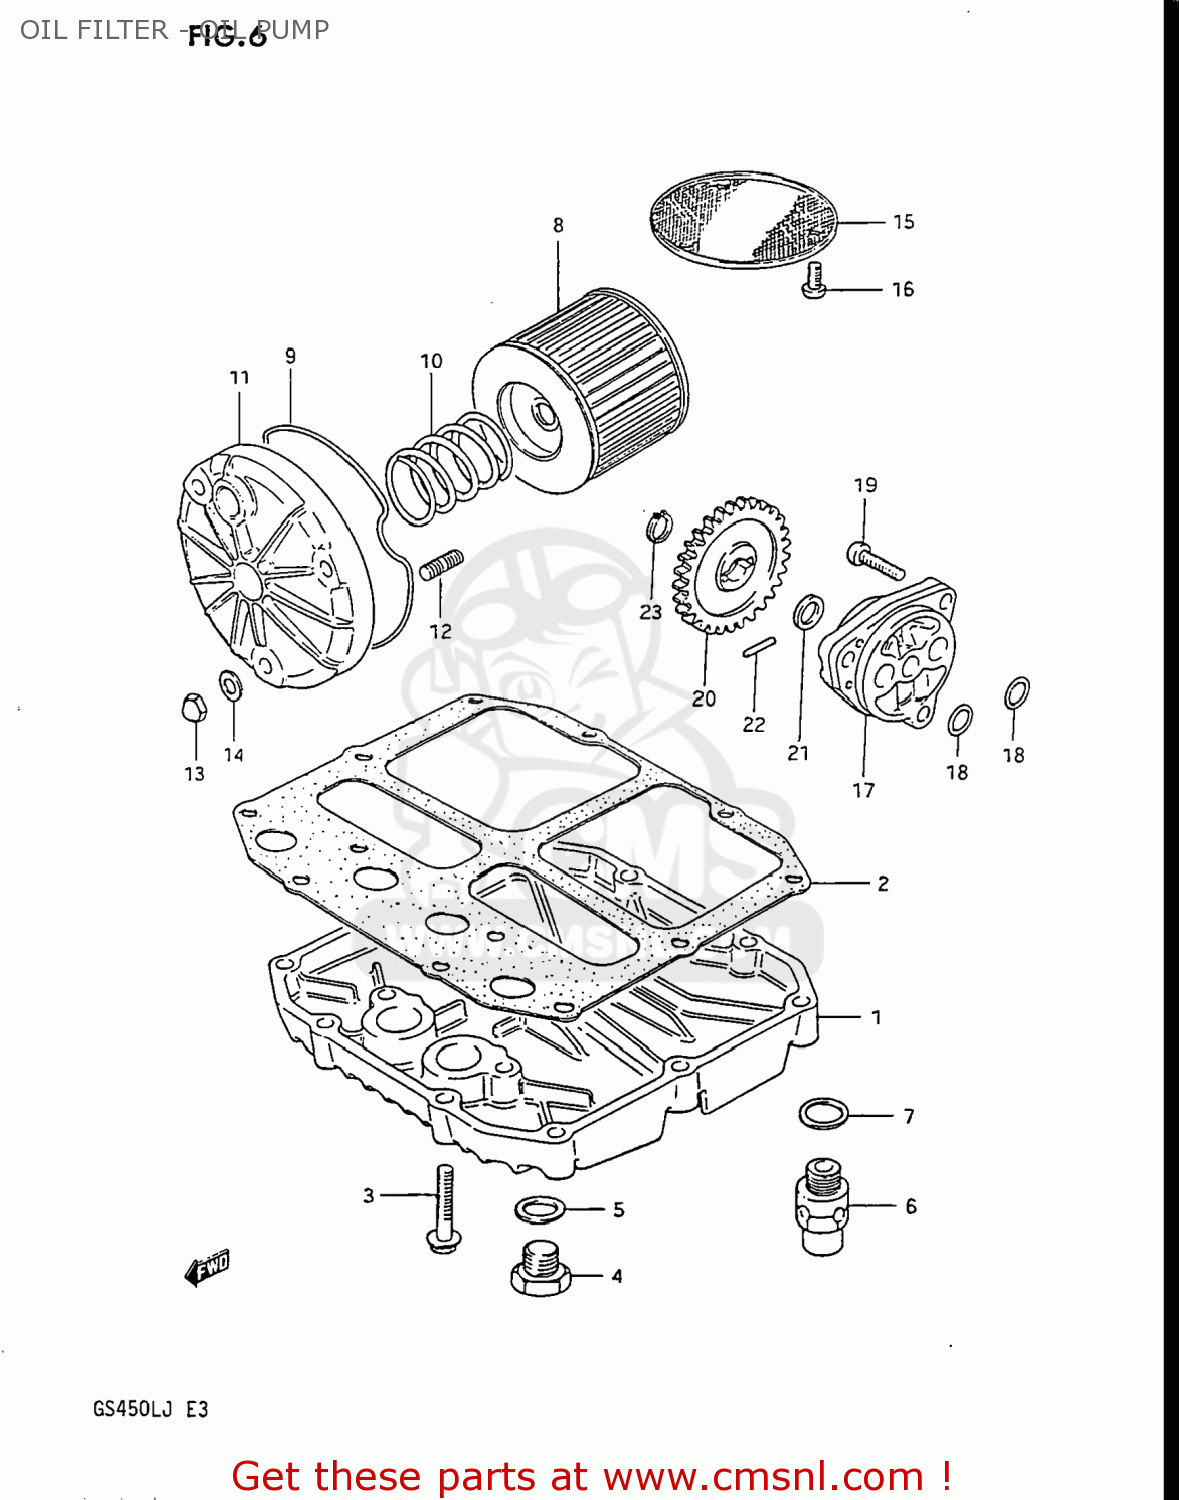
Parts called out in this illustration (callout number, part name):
1	PAN,OIL
2	GASKET,OIL PAN (MCA)
3	BOLT 6X30
4	PLUG
5	GASKET(14X19.2X2) (NAS)
6	VALVE ASSEMBLY,OIL RELIEF
7	WASHER
8	FILTER ASSY,ENGINE OIL
9	O RING,OIL FILTER CHAMBER CAP
10	SPRING
11	CAP,OIL FILTER
12	STUD 6X20
13	NUT 6MM
14	WASHER
15	STRAINER,ENGINE OIL
16	SCREW 6X12
17	PUMP ASSY,ENGINE OIL
18	O RING(D:1.9,ID:13)
19	SCREW
20	GEAR,OIL PUMP DRIVEN
21	SHIM
22	PIN(4X15.8)
23	CIRCLIP
